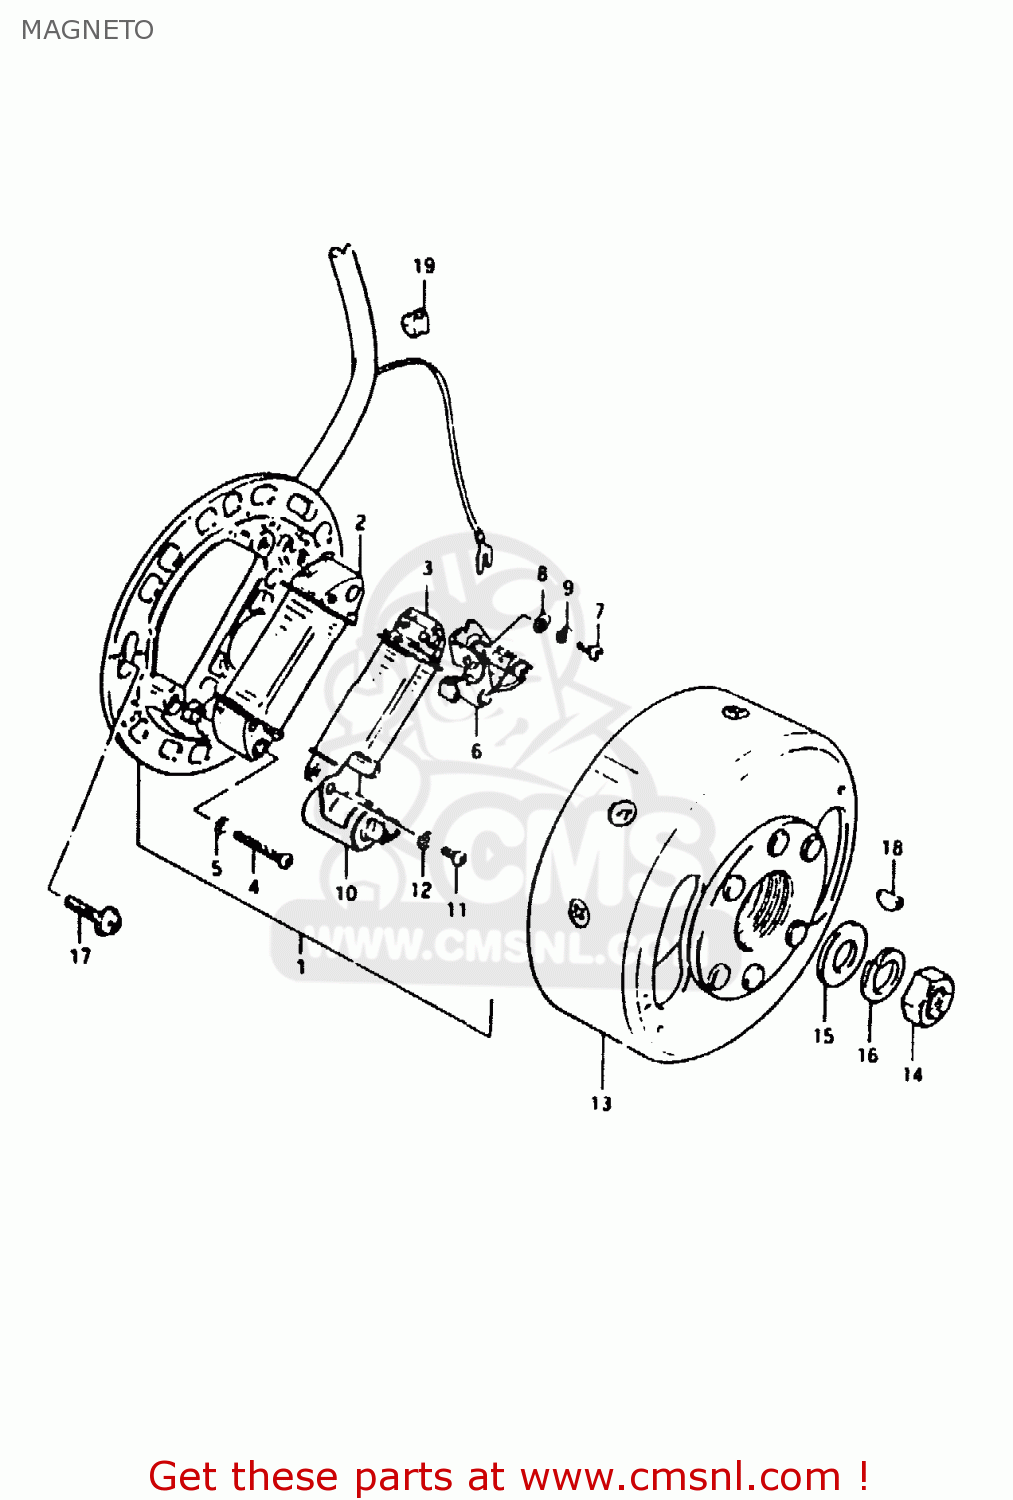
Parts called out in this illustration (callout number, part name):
1	STATOR ASSY
2	COIL,LIGHTING
3	COIL,PRIMARY
4	SCREW (4X30)
5	LOCK WASHER
6	POINT ASSY,CONTACT
7	SCREW(4X10)
8	WASHER
9	LOCK WASHER
10	CONDENSER
11	SCREW
12	LOCK WASHER
13	ROTOR, FLYWHEEL
14	NUT (10MM)
15	WASHER
16	LOCK WASHER
17	SCREW(5X14)
18	KEY
19	GROMMET,NEUTRAL LEAD WIRE
